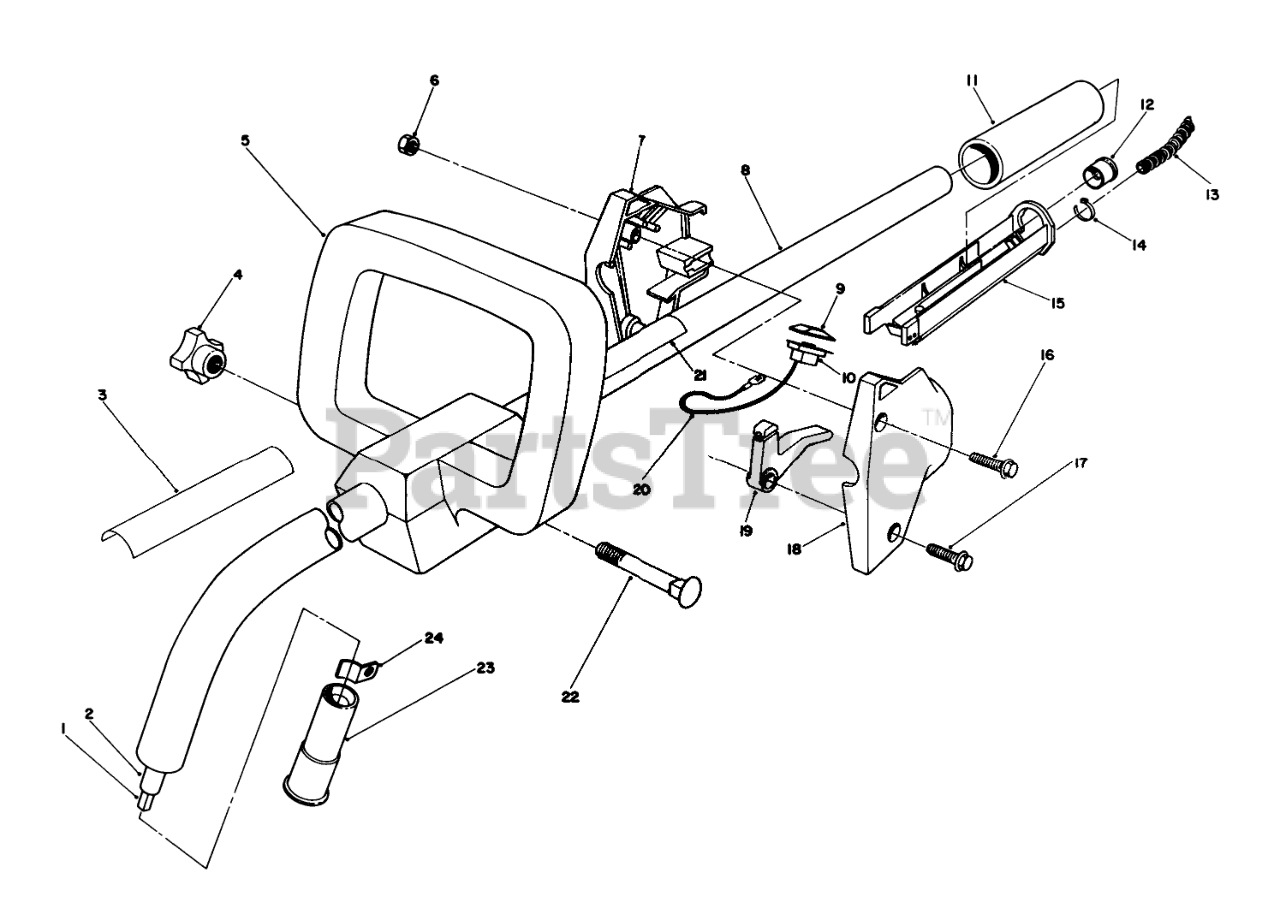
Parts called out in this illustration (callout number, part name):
1	FLEX SHAFT
2	Flex Shaft Liner
3	Decal-Model No.
4	Knob
5	SECONDARY HANDLE
6	NUT-LOCK, NI
7	THROTTLE HSG R H 1"
8	Tube-Curved
9	SWITCH COVER-BLACK
10	SWITCH
11	GRIP-RUBBER
12	BUSHING
13	Cover-Cable
14	TIE-CABLE
15	TROUGH
17	SCREW-HWH
18	THROTTLE HSG L H 1"
19	THROTTLE LEVER
20	WIRE ASM
21	Decal
22	BOLT-CARRIAGE
23	INSERT-POLE END
24	LOWER TUBE RETAINER
